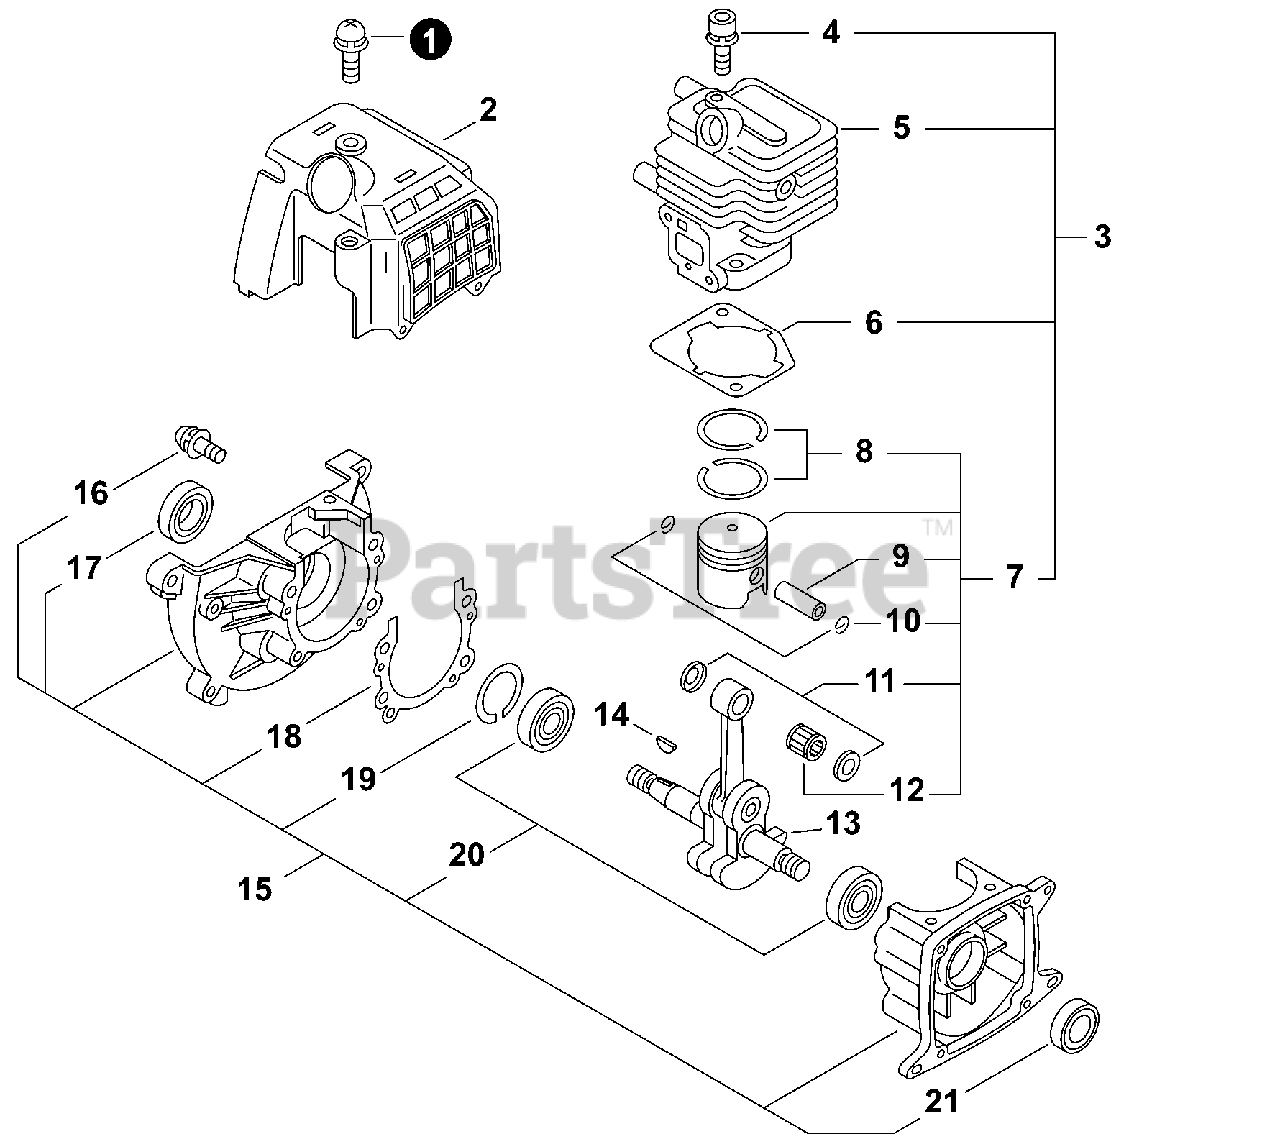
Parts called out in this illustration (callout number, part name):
1	SCREW 5x14
2	COVER, CYLINDER
3	REPAIR KIT, ENGINE
4	BOLT 5x22
5	CYLINDER
6	GASKET, CYLINDER
7	PISTON KIT
8	RING, PISTON
9	PIN, PISTON
10	RING, SNAP
11	WASHER, THRUST
12	BEARING, NEEDLE 8
13	CRANKSHAFT
14	KEY, WOODRUFF
15	CRANKCASE KIT
16	SCREW 5x25
17	SEAL, OIL 12
18	GASKET, CRANKCASE
19	RING, SNAP 28
20	BEARING, BALL 6001
21	SEAL, OIL 12
